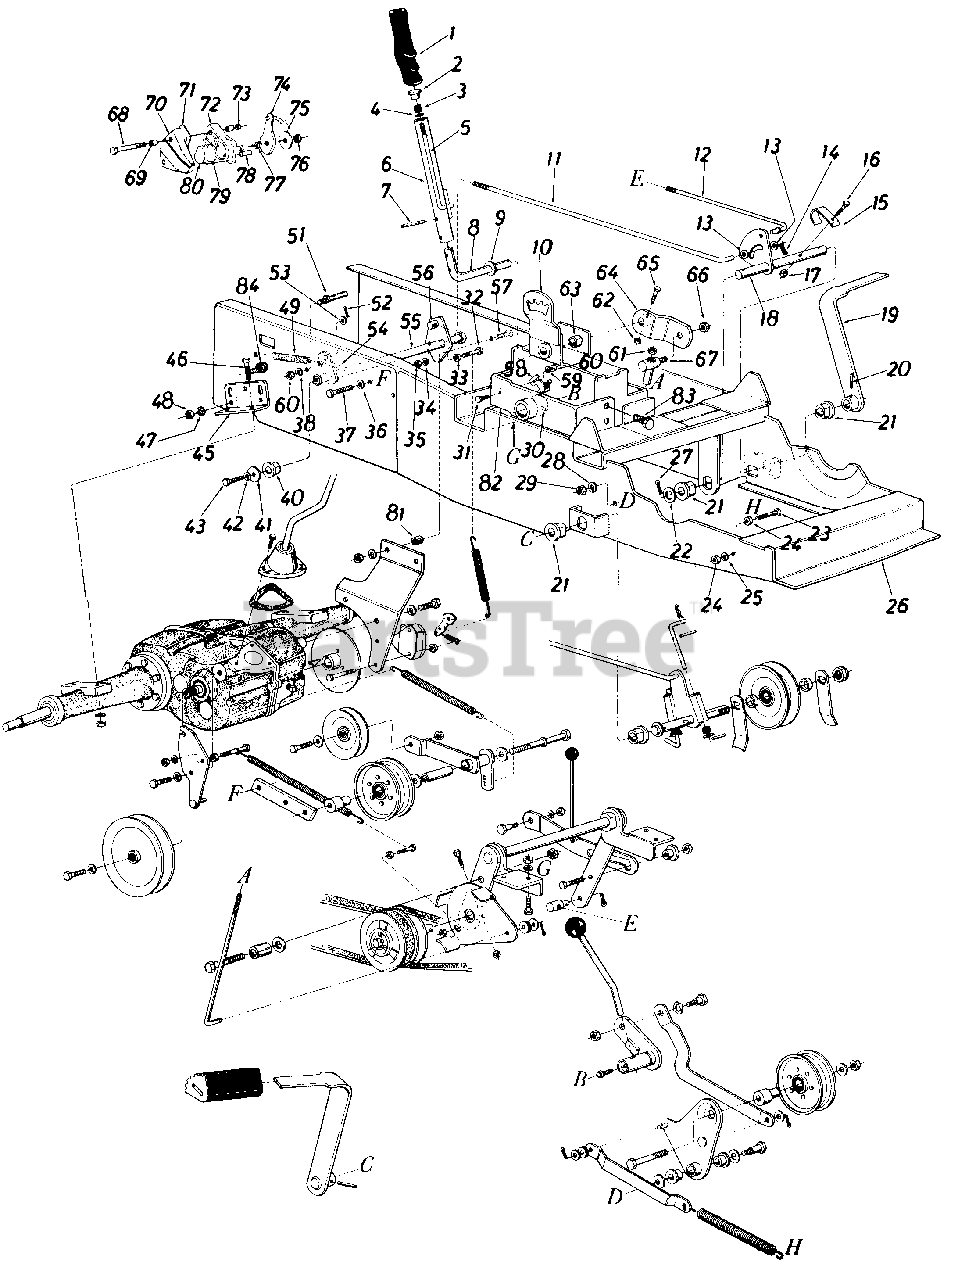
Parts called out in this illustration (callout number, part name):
2	Handle Button
3	Compression Spring
4	Fl-Wash. 1/4" I.D. x 5/8" O.D.
5	Control Rod
6	Variable Speed Handle Ass'y.
7	Spring Pin Spiral 3/16" Dia. 1" Lg.
8	Pivot Shaft
9	Fl-Wash. 5/8" x 1-1/8" O.D.
10	Variable Speed and Steering Brkt.
11	Brake Rod
12	Clutch Control Rod
13	Fl-Wash. .38 I.D. x .62" O.D.
14	Cotter Pin 1/8" Dia. x .75" Lg. *
15	Clutch Control Switch Plate
16	Hex Scr. 1/4-28 x 1.25" Lg.
17	Hex Cent. L-Nut 1/4-28 Thd.
18	Clutch Control Brkt.
19	Foot Pedal Brkt.
20	Roll Pin 1/4" Dia. x 1.50" Lg. *
21	Hex Flange Brg. Plastic
22	Fl-Wash. .75" I.D. x 1.50" O.D.
23	Hex Scr. 5/16-18 x 1.50" Lg.
24	Hex Nut 5/16-18 Thd.
25	L-Wash. 5/16" Scr.
26	Frame Ass'y.
27	Cotter Pin 1/8" Dia. x 1.25" Lg.
28	L-Wash. 3/8" Scr.*
29	Hex Top L-Nut 3/8-16 Thd.
30	Grease Fitting
31	Hex Scr. 1/4-20 x .50" Lg.
32	Hex Scr. 5/16-18 x 1.25" Lg .
33	Hex Nut 5/16-18 Thd.
34	L-Wash. 5/16" Scr.
35	Hex Nut 5/16-18 Thd.
36	L-Wash. 5/16n Scr.*
37	Hex Scr. 3/8-16 x .75" Lg.*
38	L-Wash. 1/4" Scr.
40	Hex Brg. .630 I.D.
41	Fl-Wash. 5/16" I.D. x 1.125" O.D.
42	L-Wash. 5/16" Scr.*
43	Plastic Ms. Hex Scr. 5/16-16 x 1.50" Lg.
45	Transaxle Support Brkt.
46	Hex Scr. 3/8-16 x 1.75" Lg.
47	L-Wash. 3/8" Scr. H.D.
48	Hex Nut 3/8-24 Thd.*
51	Belt Guard Pin 1/4-20 x 1.68" Lg.
52	Cotter Pin 1/8" Dia. x .75" Lg.*
53	Fl-Wash. .38" I.D.
54	Brake Rod Ass'y.
55	Brake and Clutch Jackshaft
56	Ferrule
57	Hex Scr. 5/16-18 x 1.25" Lg.*
58	Safety Switch
59	L-Wash. 1/4" Scr*
60	Hex Nut 1/4-20 Thd.*
61	Hex Jam Nut 3/8-24 Thd.
62	Hex Cent. L-Nut 1/4-28 Thd.
63	Flange Brg.
64	Actuator Arm Ass'y.
65	Hex Scr. 1/4-28 x 1.25" Lg.
66	Hex Cent. L-Nut 5/16-18 Thd.
67	Ferrule Ass'y.
68	Hex Scr. 3/8-16 x 3.50" Lg.
69	Spacer
70	Casting-Carrier Side
71	Spacer
72	Casting-Cam Side
73	Hex Cent. L-Nut 3/8-16 Thd.
74	Cam Lever
75	Thrust Wash. 5/16" I.D.
76	Hex Nut 5/16-24 Thd.
77	Compression Spring
78	Push Pin
79	Disc-Back Up
80	Pad-Friction
81	Spacer .380 I.D. x 1.0" O.D. x .315
82	PTO Mtg. Brkt. Ass'y.
83	Hex Scr. 5/16-18 x 75" Lg.
84	Rd. Hd. R/B Neck Bolt 3/8-24 x 1.00" Lg.
